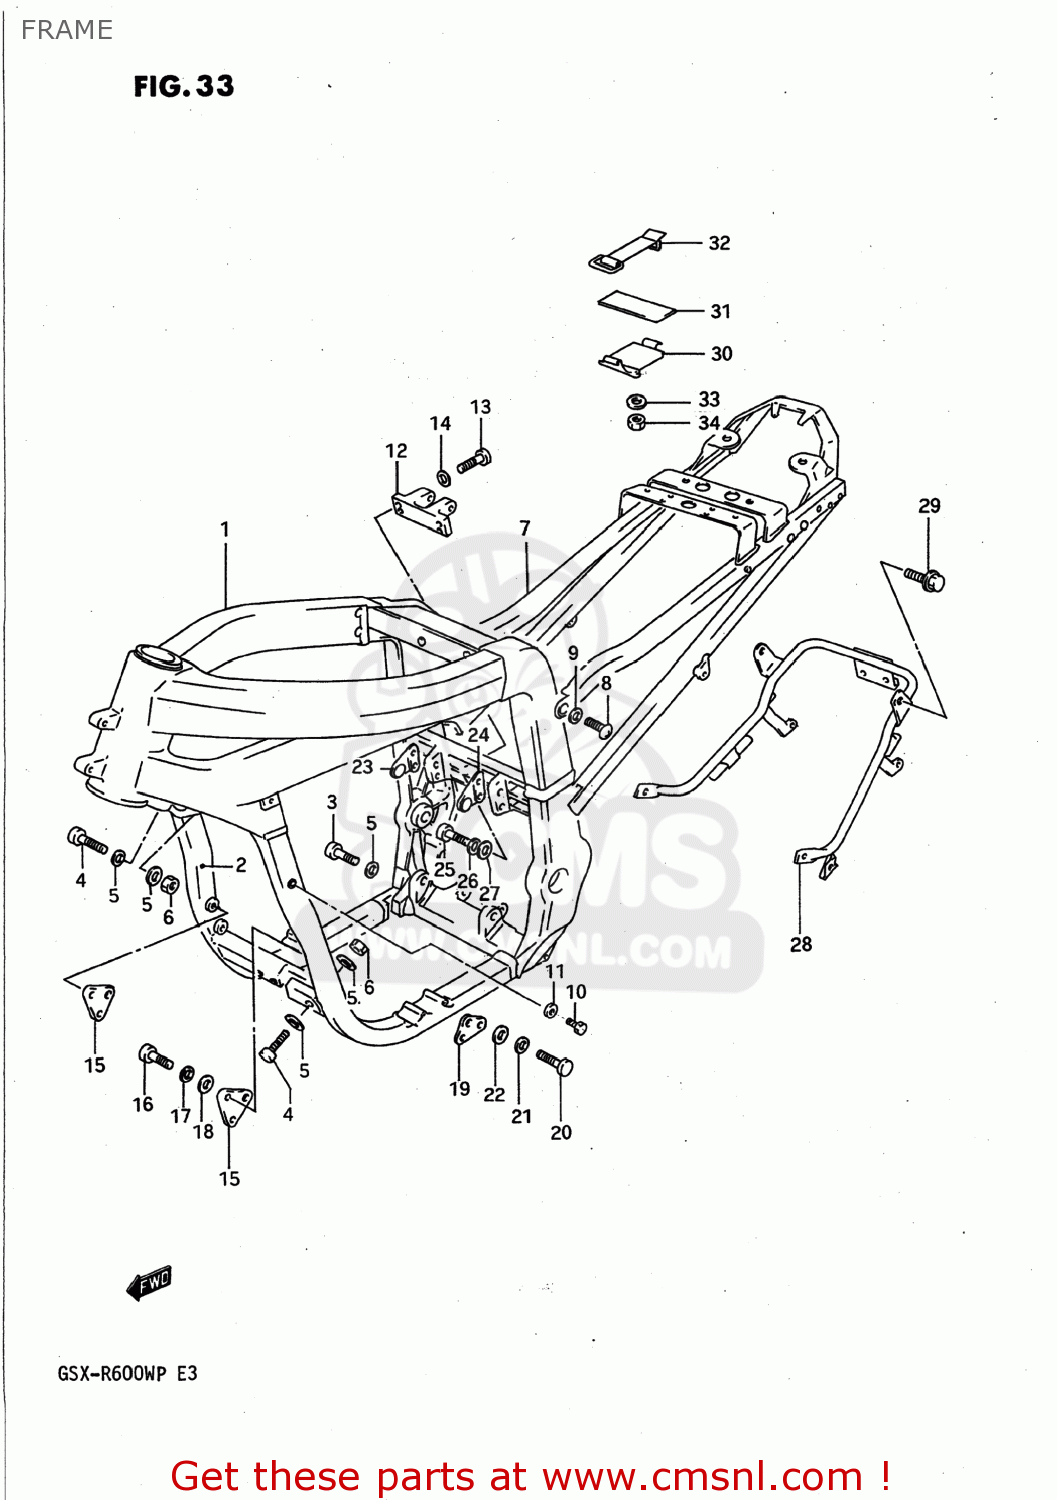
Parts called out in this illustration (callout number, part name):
1	FRAME
2	TUBE,FRAME
3	BOLT
4	BOLT
5	WASHER (10.1X21X2.3)
6	NUT
7	RAIL,SEAT
8	BOLT,FOOTREST BRACKET
9	WASHER
10	BOLT
11	GASKET(6.2X11X1) (NAS)
12	BRACKET,R.C.U.
13	BOLT(8X28)
14	WASHER
15	PLATE,ENG MTG NO.1
16	BOLT, FRONT LH
17	WASHER,LOCK
18	WASHER (8.2X20X1.6)
19	PLATE,ENG MTG NO.2,R
20	BOLT, FRONT LH
21	WASHER,LOCK
22	WASHER (8.2X20X1.6)
23	PLATE,ENGINE MOUNTING NO.3
24	PLATE,ENG MTG NO.3,L
25	BOLT(8X22)
26	WASHER,LOCK
27	WASHER (8.2X20X1.6)
28	GRIP COMP,REAR
29	BOLT
30	HOLDER,TOOL
31	COVER,HARNESS
32	BAND
33	WASHER
34	NUT
